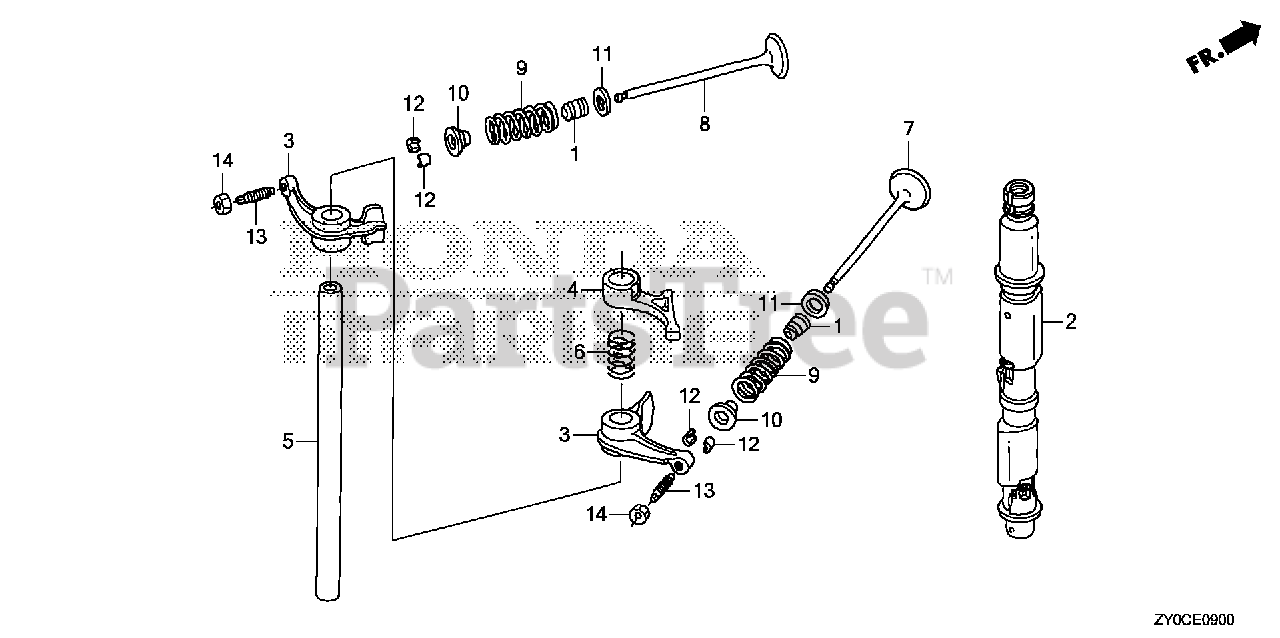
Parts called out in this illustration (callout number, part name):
1	SEAL, VALVE STEM (ARAI)
3	ARM, VALVE ROCKER
4	ARM, FUEL PUMP ROCKER
5	SHAFT, ROCKER ARM
6	SPRING, ROCKER ARM
7	VALVE, IN.
8	VALVE, EX.
9	SPRING, VALVE
10	RETAINER, VALVE SPRING
11	SEAT, VALVE SPRING
12	COTTER, VALVE
13	SCREW, TAPPET ADJUSTING
14	NUT, TAPPET ADJUSTING
